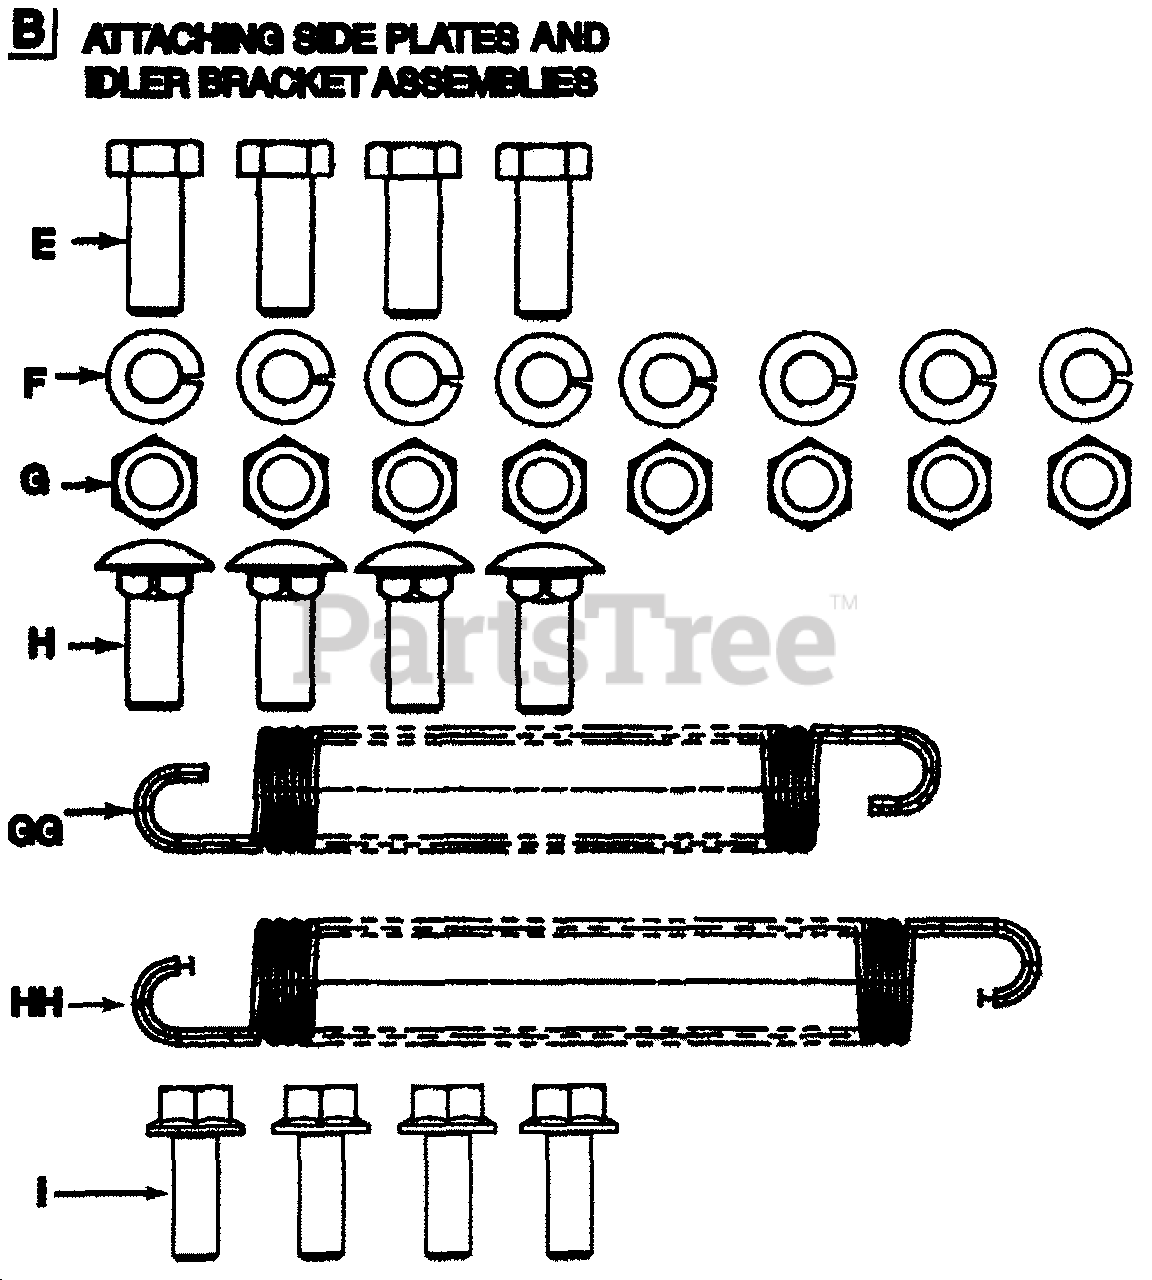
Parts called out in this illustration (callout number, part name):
E	Hex Bolts 3/8-16 x 1" Long
F	Lock Washers 3/8" I.D.
G	Hex Nuts 3/8-16 Thread
H	Carr. Bolts 3/8-16 x 1" Long
I	Hex Tap Screw 5/16 x 7/8" Long
GG	Extension Spring 5.5" Long
HH	Extension Spring 6.12" Long
